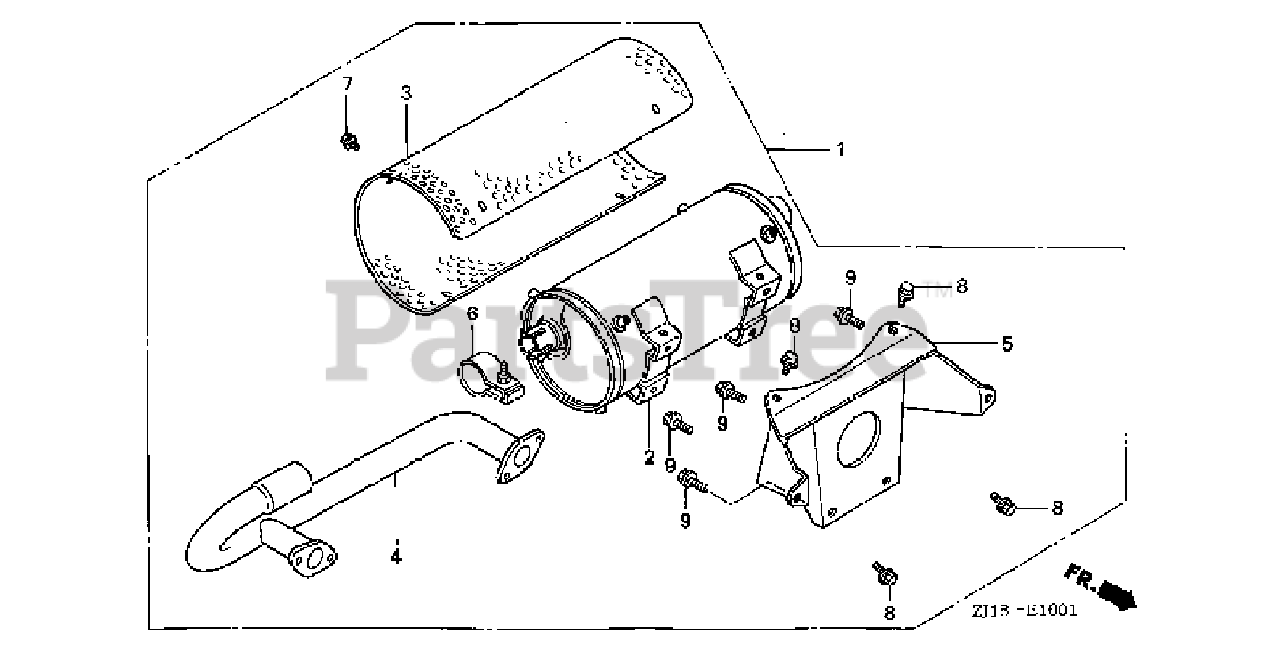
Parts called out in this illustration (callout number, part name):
1	MUFFLER KIT (HIGH-A) (N/A: SEE COMPONENTS)
2	MUFFLER (HIGH)
3	PROTECTOR, MUFFLER (HIGH)
4	PIPE, EX. (HIGH-R)
5	STAY, MUFFLER (HIGH)
6	BAND ASSY.
7	BOLT, FLANGE (6X8)
8	BOLT, FLANGE (8X14)
9	BOLT, FLANGE (8X20)
